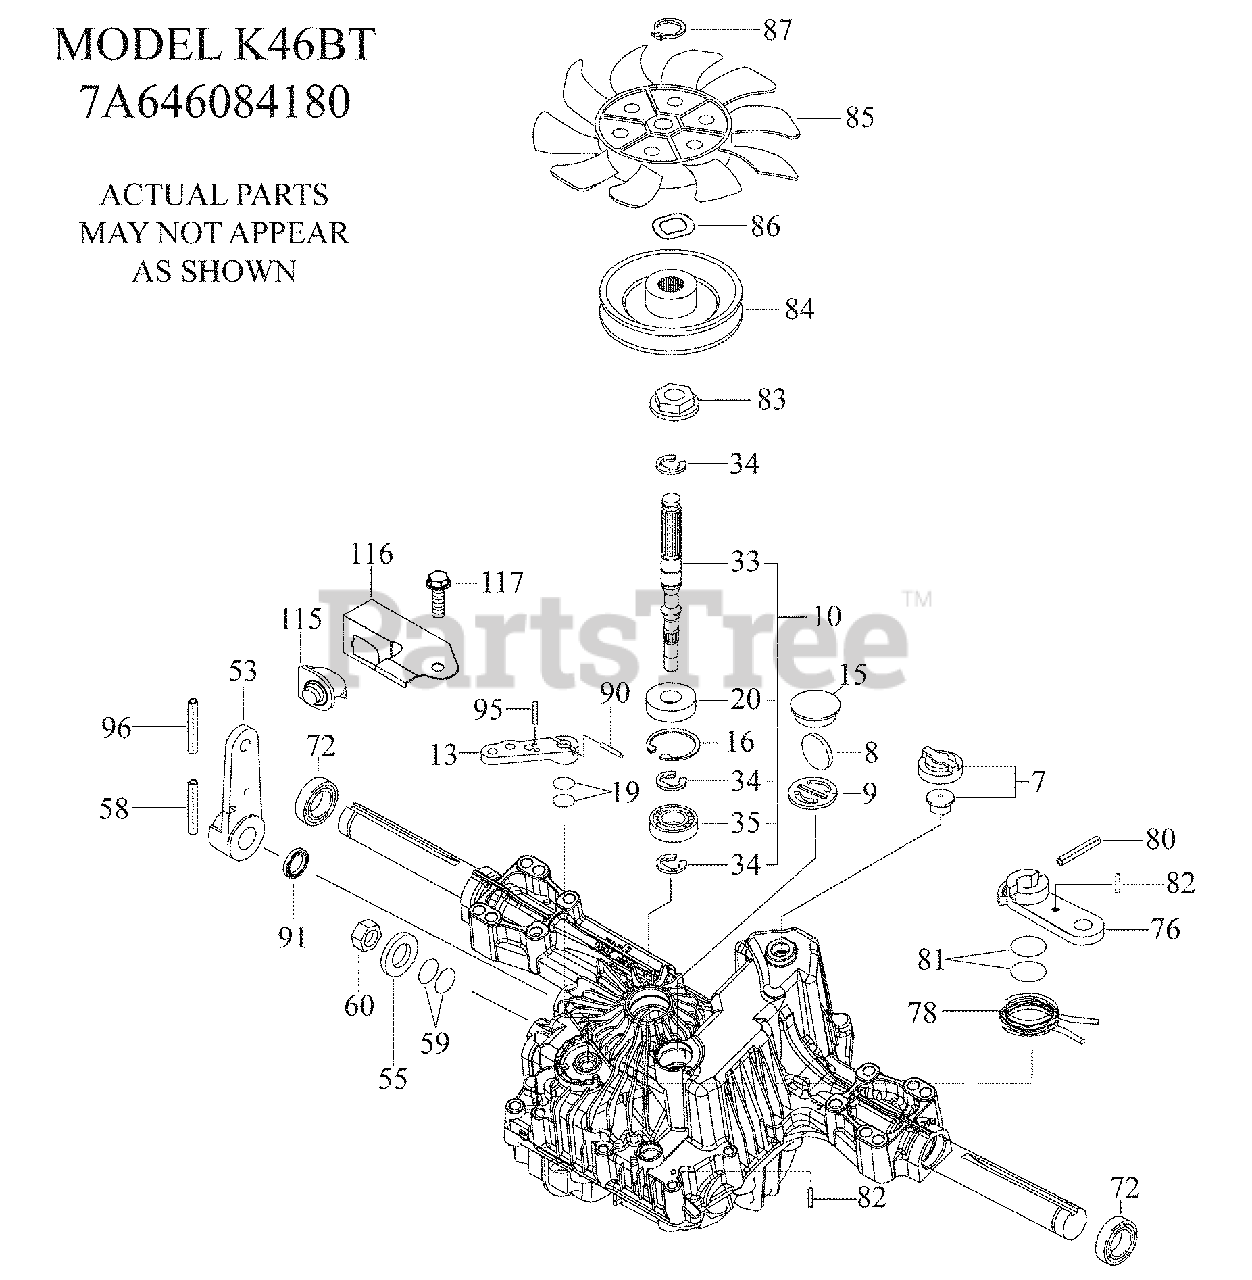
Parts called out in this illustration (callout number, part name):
7	Vent Valve 15
8	Magnet
9	Magnet Holder
10	Pump Shaft/Bearing Kit
13	Bypass Lever
15	Sealing Cap 30
16	Snap Ring C 35
19	O-Ring 1a P10a
20	Seal Tc 153507
33	Pump Shaft
35	Bearing 6202c3
53	Control Lever F
58	Roll Pin 6 * 40
59	O-Ring 1a P14
72	Seal 19 * 32 * 8
76	Brake Lever
78	Brake Return Spring
80	Spring PIn 5 * 32
81	0-Ring 1a P12
82	Spring Pin 4 * 16
83	Spine Collar
84	Pulley L
85	Fan, Black
86	Wave Washer
87	Snap Ring
90	Spring Pin 3.0a * 20
91	Oil Seal 16 * 22 *.03
95	Spring Pin 3.0a*16
96	Roll Pin 3.5 * 40
115	Switch 6440-11 Delta
116	Switch Bracket
117	Tapping Screw 8 * 20
